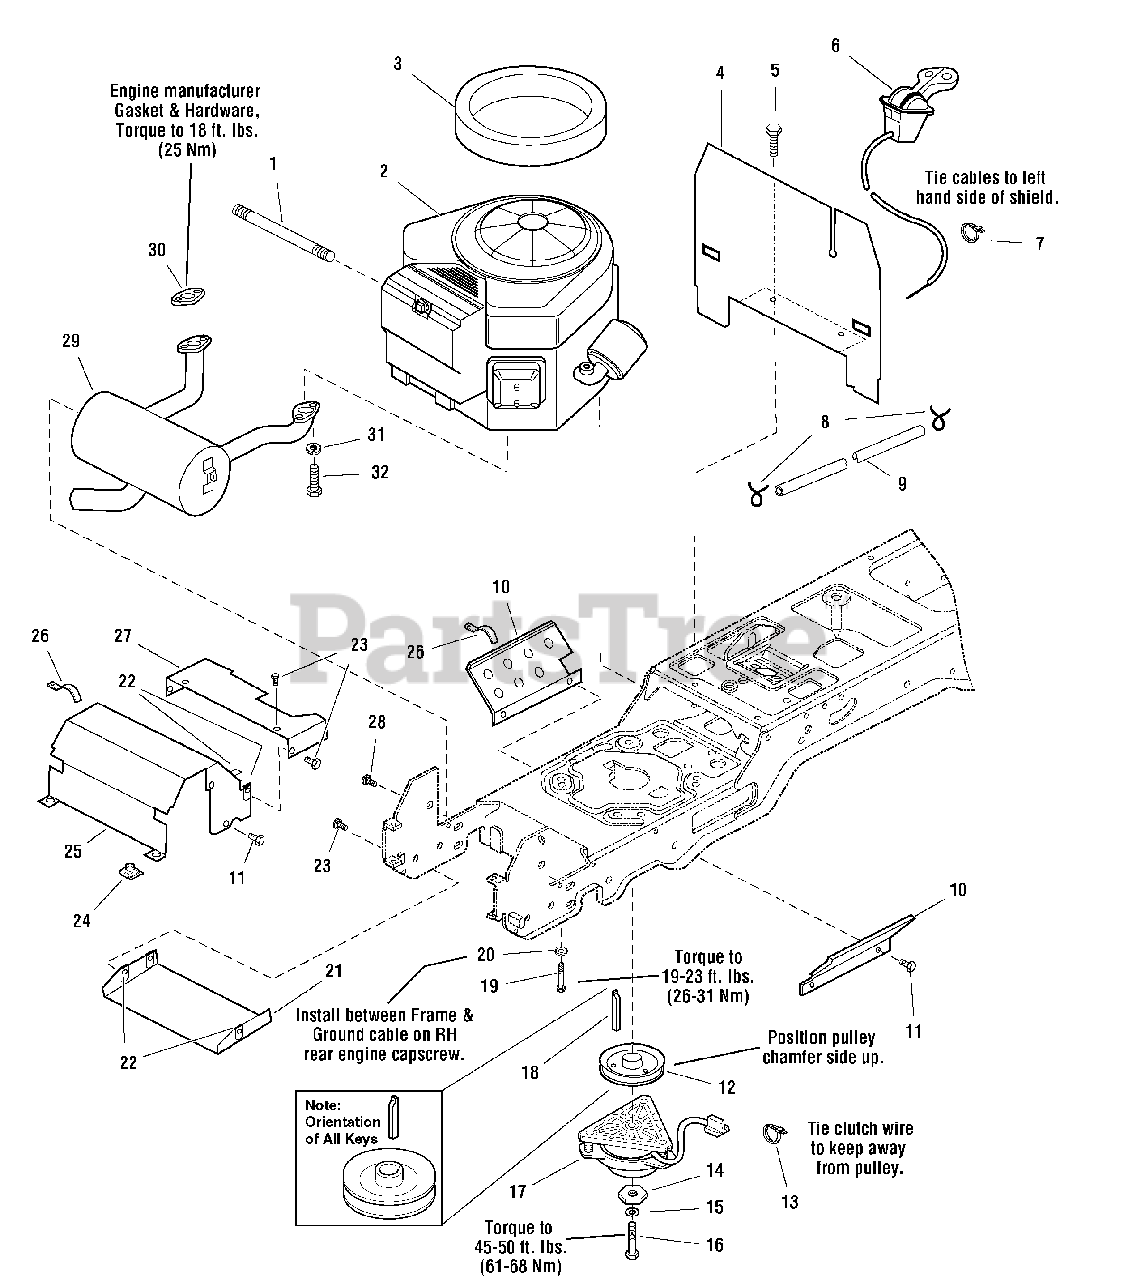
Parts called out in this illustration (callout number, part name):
1	HOSE, Oil Drain, 10-1/2 Long, 3/8-18 Fittings
3	SEAL, Circle
5	CAPSCREW, Hex Washer Head Taptite, 1/4-20 x 1/2, Black
6	CONTROL, Throttle Double, 39" Long, w/Knobs
8	CLAMP, Hose Type E
9	HOSE, Fuel, 58" Long
10	SHIELD, Side
11	CAPSCREW, Hex Washer Head Taptite, 1/4-20 x 3/8
12	PULLEY & HUB ASSEMBLY
13	TIE, Self Locking, 3-5/8 Long
14	WASHER, Hex, 7/16, 1/4, Black
15	LOCKWASHER, 7/16
16	CAPSCREW, Hex Head, 7/16-20 x 3-1/2
17	CLUTCH, Electric, Ogura
18	KEY, HI PRO, 1/4 x 2-1/2
19	CAPSCREW, Hex Washer Head Taptite 3/8-16 x 1-1/2
20	LOCKWASHER, External Tooth, 3/8
21	SHIELD, Muffler Bottom
22	NUT, Speed, 1/4-20, Lug
23	CAPSCREW, Hex Flange Whiz Lock, 1/4-20 x 5/8
24	NUT, Speed, 1/4-20, Lug
25	DUCT, Muffler Top
26	CLIP, Wire
27	DUCT, Muffler Extension
28	CAPSCREW, Hex Washer Head Taptite, 5/16-18 x 1/2, Black
29	MUFFLER, Briggs & Stratton, Vanguard Twin
30	GASKET, Briggs & Stratton, Vanguard Twin
31	LOCKWASHER, 1/4
